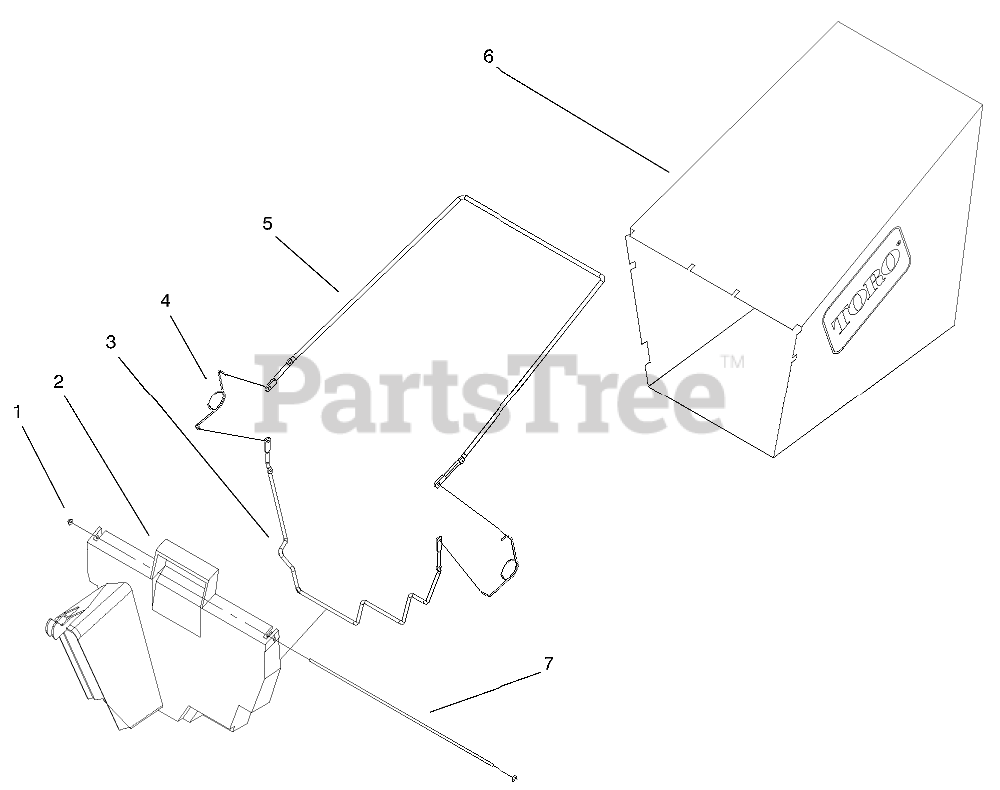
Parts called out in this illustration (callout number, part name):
1	Nut-Push (Only On: 20025)
2	Door-Bag (Only On: 20025)
3	Frame-Lower Bag (Only On: 20025)
4	Spring (Only On: 20025)
5	Frame-Upper Bag (Only On: 20025)
6	Bag-Grass (Only On: 20025)
7	Hinge-Bag Door (Only On: 20025)
